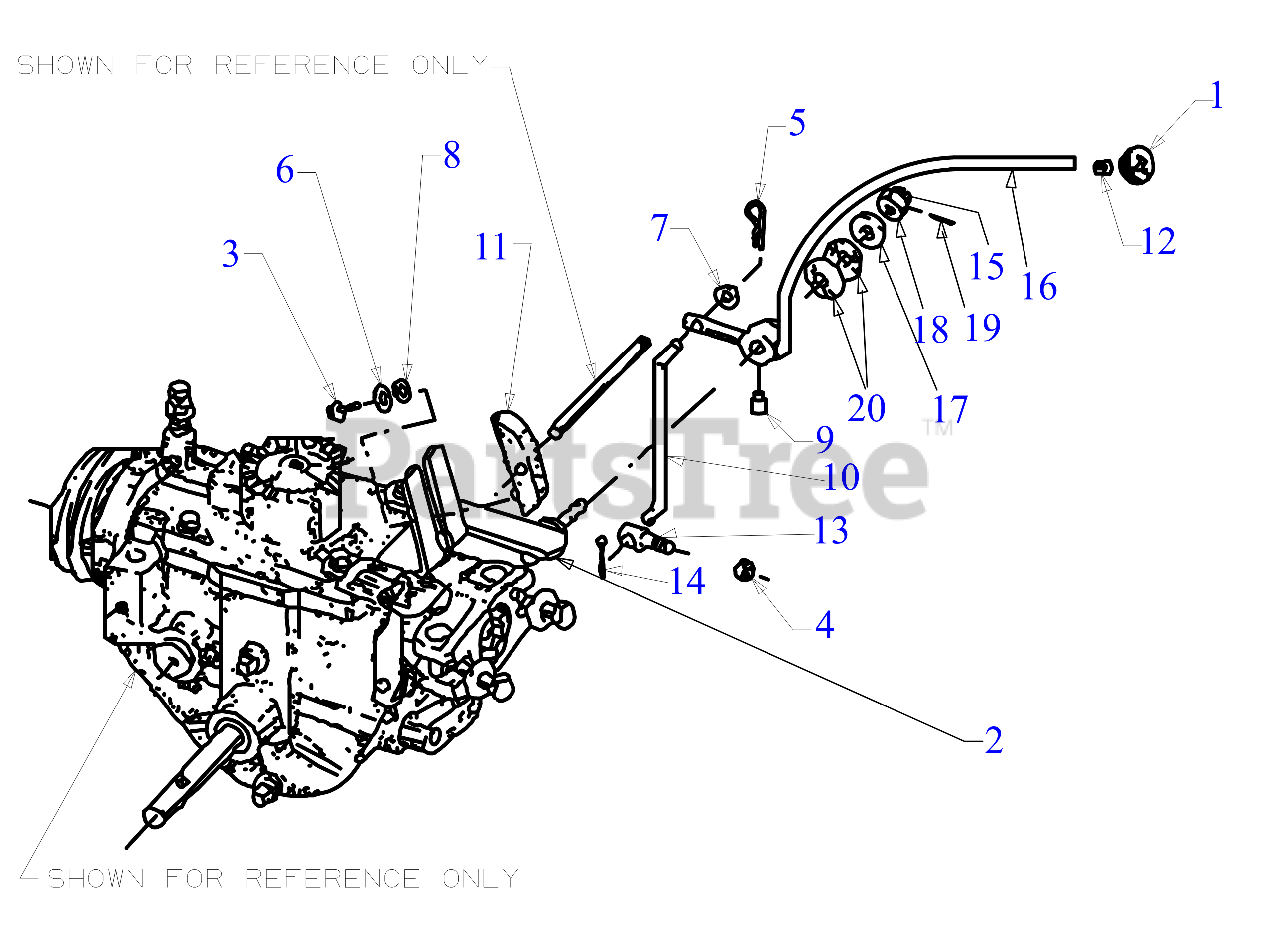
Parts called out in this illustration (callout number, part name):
1	WHEEL SPEED KNOB
2	SHIFT LEVER BRACKET
3	SCREW 3/8-16 x 1 GR5
4	HEX NUT CENTER
5	COTTER PIN INT
6	LOCK WASHER 3/8
7	FLAT WASHER
8	FLAT WASHER
9	GREASE FITTING
10	CONNECTING ROD
11	BELT ADJUST BLOCK
12	RING-TOLERANCE
14	COTTER PIN
15	HEX NUT CASTLE
16	WHEEL SPEED LEVER WITH KNOB
17	WASHER-#SHOULDER
18	FLAT WASHER
19	SPRING PIN
20	WASHER-#1.97X1X.11
